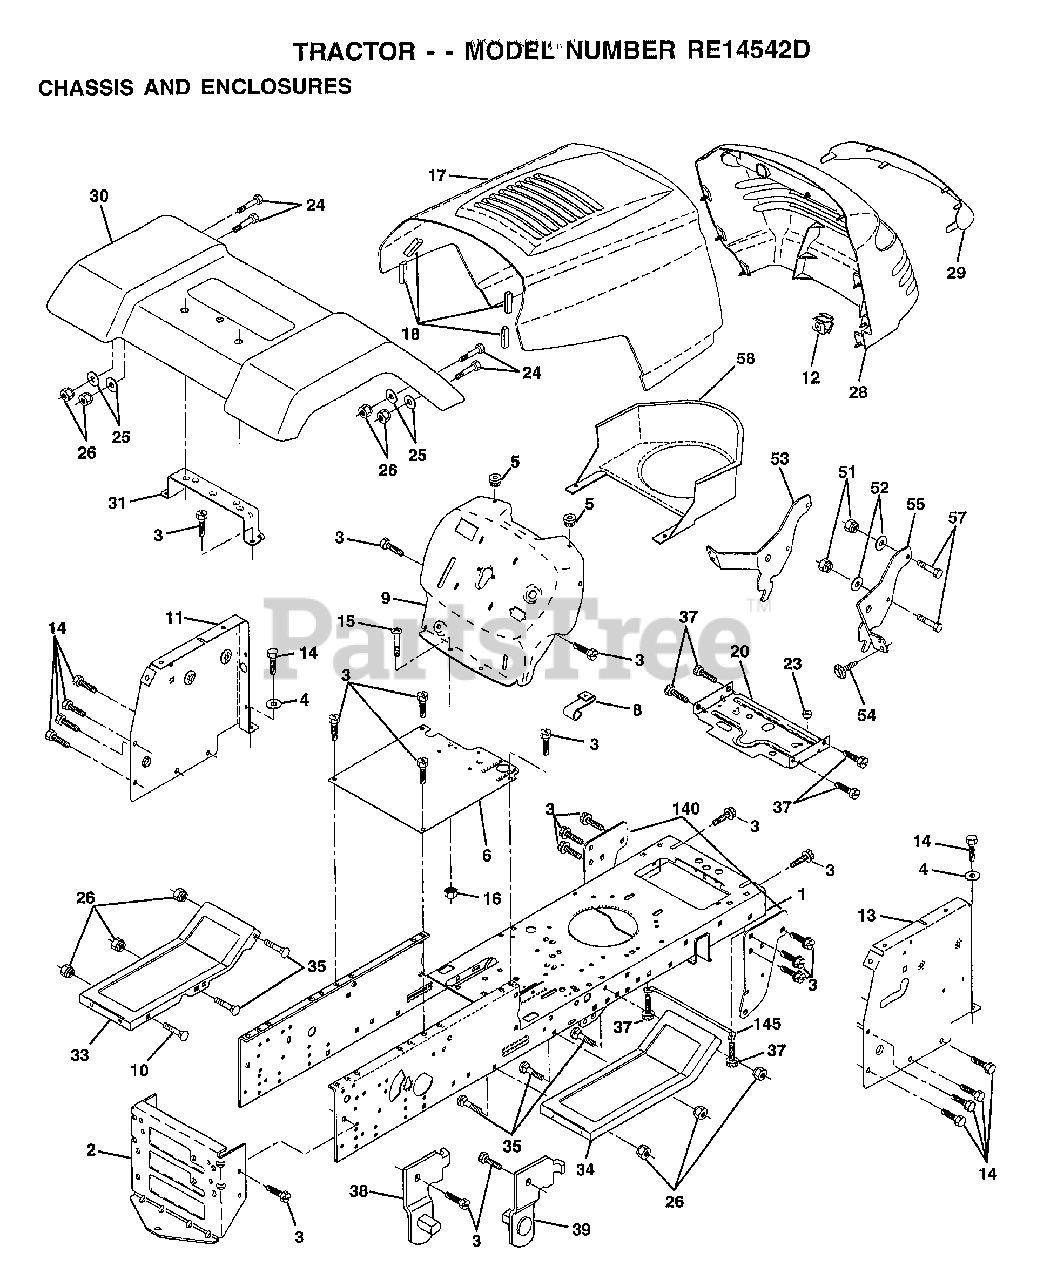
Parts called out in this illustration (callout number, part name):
1	CHASSIS.STAMPING
3	SCREW
4	WASHER
5	BUMPER-HOOD/DASH
6	SADDLE
8	CLIP.RETAINER
9	DASH SILKSCREEN
11	"PANEL-DASH,LH"
12	CLIP.TINNERMAN
13	PANEL.ASM.SLKSCR.DASH.RH
14	SCREW LT
15	SCREW
17	HOOD.STEEL.ASSY
20	"PLATE-MTG,BATT/FU"
24	BOLT
25	WASHER
26	NUT
28	GRILLE-MS428
29	LENS.GRILLE.PRIVATE LABEL
31	BRKT FENDER
33	FOOTREST LH
34	FOOTREST RH
35	BOLT
37	SCREW LT
38	BRACKET ASM LH
39	BRACKET ASM RH
51	NUT
52	WASHER
53	BRACKET.GRILLE.LH
54	SCREW.HEX.WS.HD
55	BRACKET.GRILLE.RH
58	DUCT.AIR.B&S.18HP
140	BRKT SUSPENSION
145	"ROD POVOT,CHASSIS"
